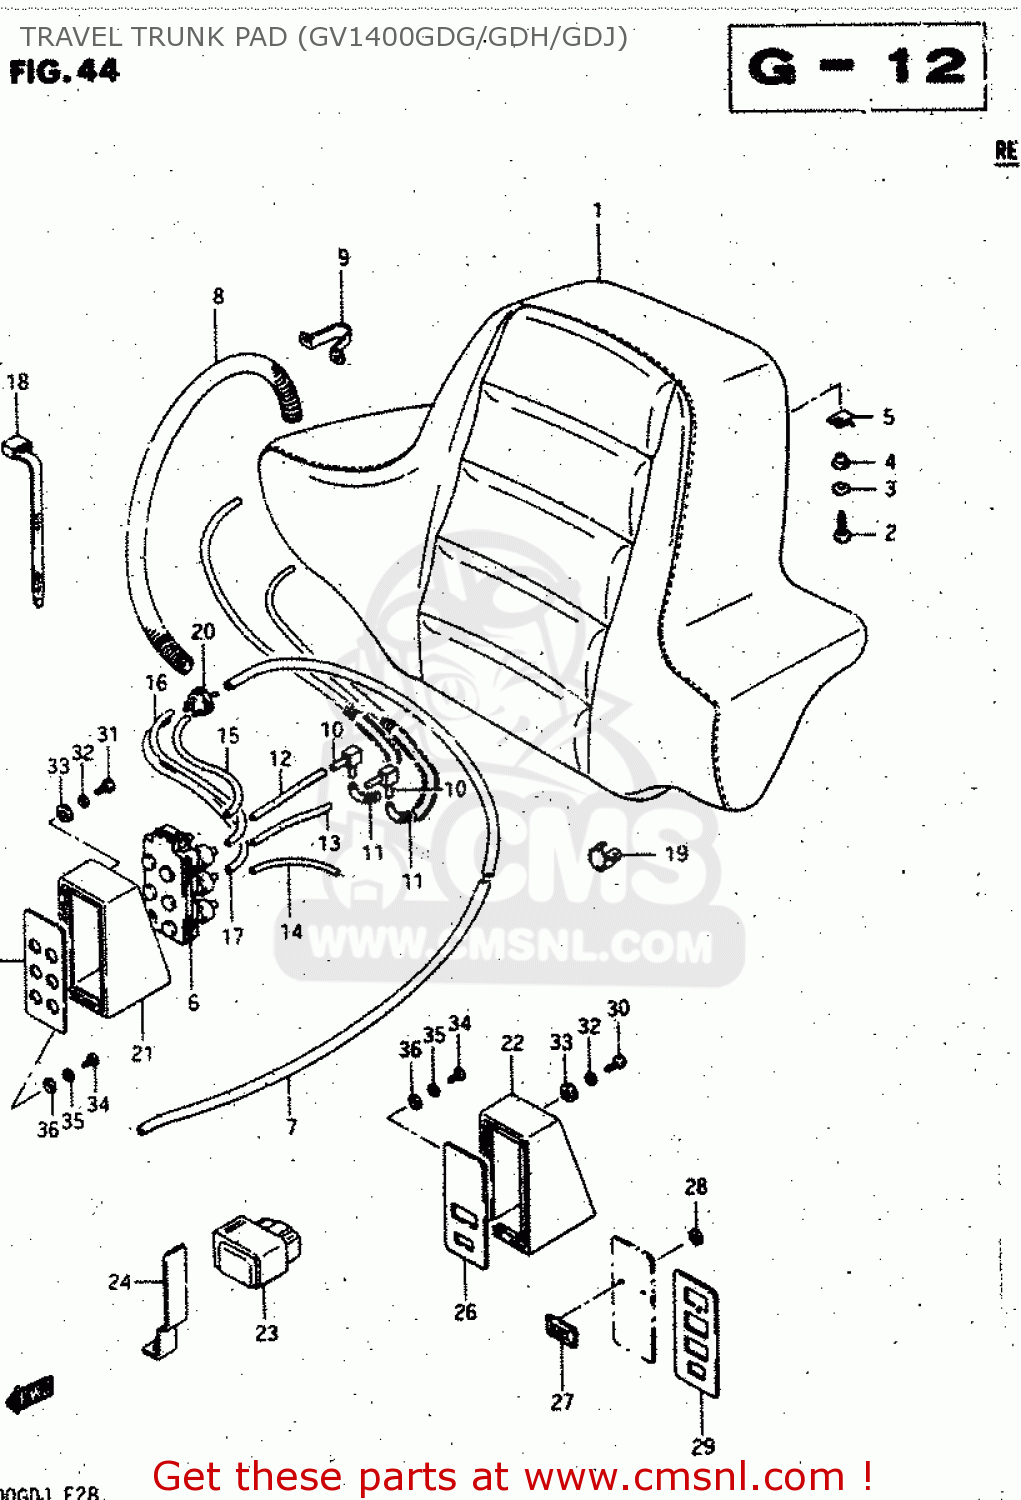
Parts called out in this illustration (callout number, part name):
1	PAD ASSEMBLY
2	SCREW
3	WASHER
4	SEAL,PAD ASSEMBLY,RIGHT
5	NUT
6	VALVE ASSEMBLY,SEAT
7	MOLDING,SEAT,LEFT
8	PROTECTOR, TRUNK HOSE
9	HOLDER, TRUNK HOSE
10	UNION
11	SPRING
12	HOSE, OUTLET NO.1
13	HOSE, OUTLET NO.2
14	HOSE, OUTLET NO.3
15	HOSE, INLET NO.1
16	HOSE, INLET NO.2
17	HOSE, INLET NO.3
18	CLAMP(L:165)
19	CLAMP
20	4-WAY
21	PAD ASSEMBLY,TRAVEL TRUNK
22	PAD ASSEMBLY,TRAVEL TRUNK
23	RELAY ASSEMBLY,SEAT
24	BRACKET, SEAT RELAY
25	PANEL COMP,VALVE ASSEMBLY
26	PANEL COMP,TUNER ASSEMBLY
27	EMBLEM
28	NUT
29	PANEL,TUNER ASSEMBLY NO
30	BOLT, PAD UPPER LH
31	BOLT, PAD
32	WASHER,LOCK
33	WASHER
34	SCREW
35	WASHER,LOCK 4M
36	WASHER 4MM
